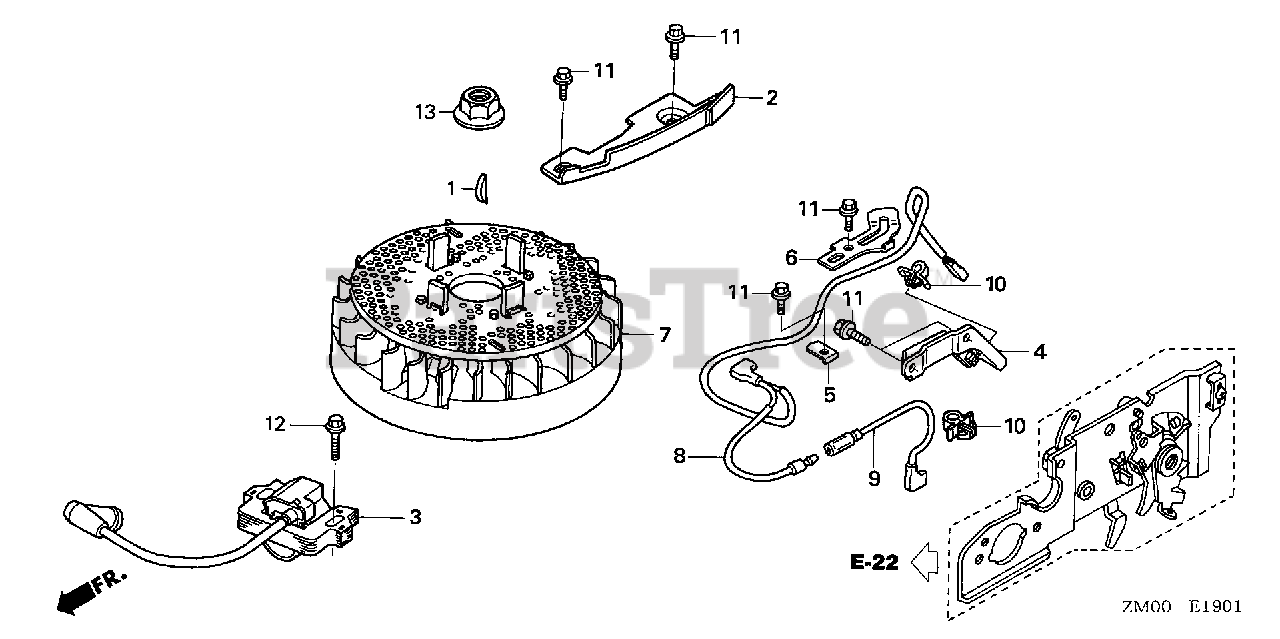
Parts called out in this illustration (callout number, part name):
1	KEY, SPECIAL WOODRUFF (25X18)
2	PLATE, SIDE
3	COIL ASSY., IGNITION (PHELON)
4	CLAMP, STOP SWITCH WIRE
5	CLAMP, STOP SWITCH WIRE
6	CLAMP, WIRE
7	FLYWHEEL ASSY. (PHELON) (USE FOR IGN. COIL OF PHELON)
8	WIRE, STOP SWITCH
9	WIRE, STOP SWITCH
10	HOLDER, WIRE (FASTEX)
10	CLIP A, CABLE (3.8MM BLACK) (NIFCO)
11	BOLT, FLANGE (6X12) (CT200)
12	BOLT, FLANGE (6X20) (CT200)
13	NUT, SPECIAL (14MM)
